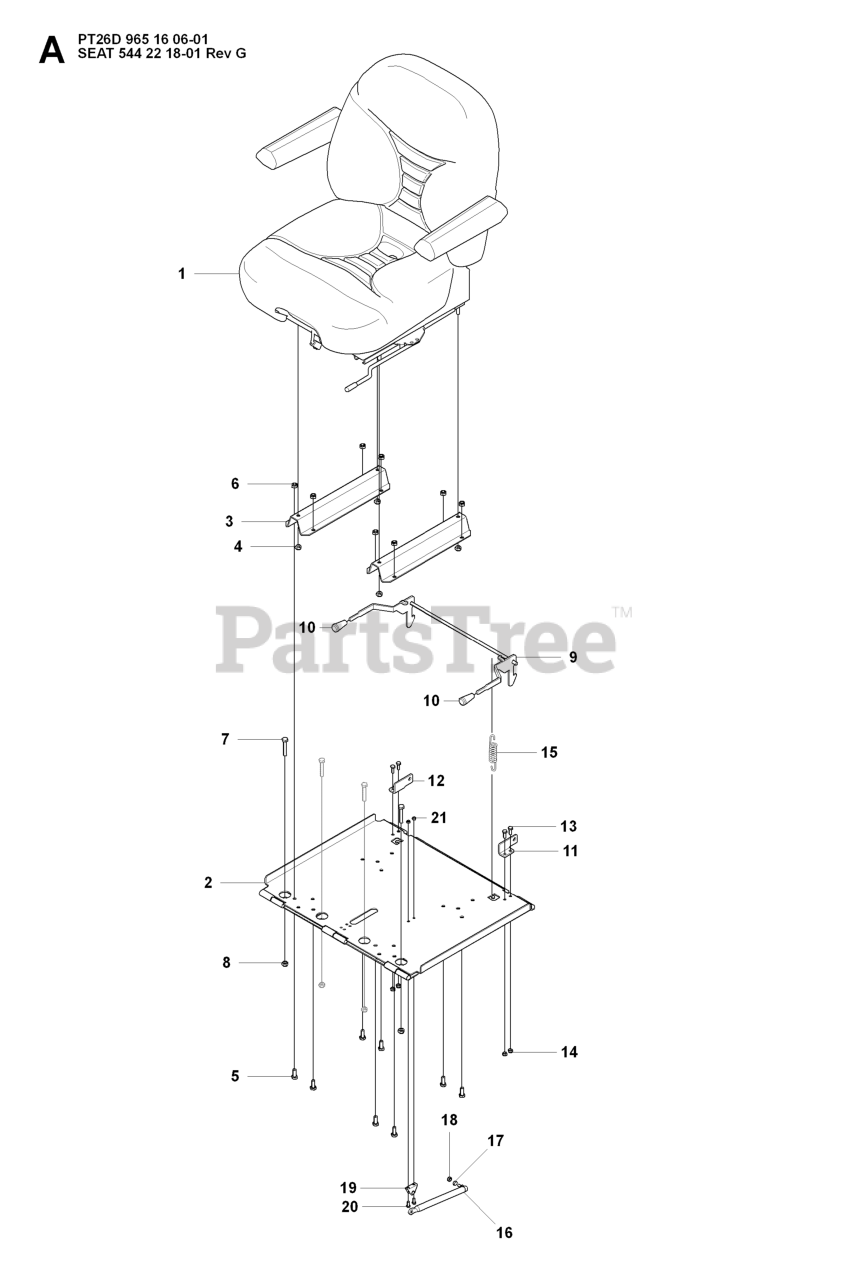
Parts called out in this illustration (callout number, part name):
4	LOCKNUT M8
5	SCREW 8X20
6	LOCKNUT M8
7	SCREW
8	LOCKNUT M8
13	BOLT FLANGE - M6X20
14	LOCKNUT M6
15	DRAW SPRING L=50
18	LOCKNUT M6
20	SCREW
21	LOCKNUT M5
